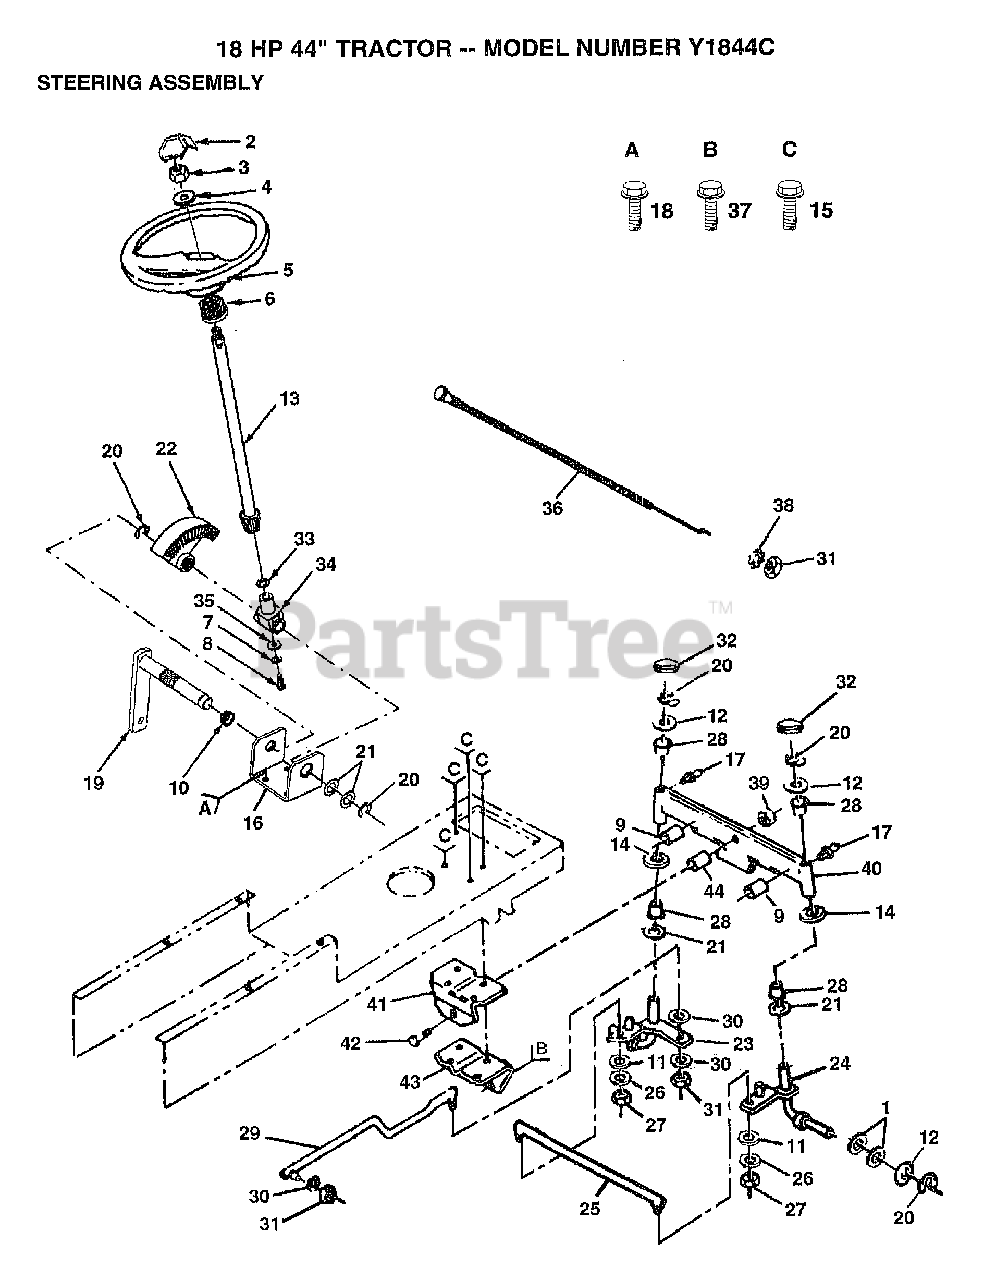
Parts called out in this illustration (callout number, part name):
1	WASHER
2	INSERT STEERING
4	WASHER
6	ADAPTER LT
7	LOCKWASHER
8	"SCREW,SPECIAL"
9	AXLE PIN
10	NYLINER T
11	WASHER M
12	WASHER
14	WASHER
15	SCREW SPECIAL
16	"BRKT,STEERING"
17	ZERK M
18	SCREW
20	RING
21	WASHER .T
22	GEAR SECTOR
23	SPINDLE LH
24	SPINDLE RH
25	TIE ROD
26	LOCKWASHER
27	NUT.LOCK.5/16-24
28	COL. SRTG. BEAR.
30	LOCKWASHER
32	CAP
33	THRUST WASHER
34	SUPPORT.SHAFT
37	SCREW LT
38	LOCKWASHER
39	"NUT-LOC,FLANGE LT"
40	FRONT AXLE
41	SUPPORT-SADDL T
42	BOLT LT
43	SUPPORT.SADDLE.FT
44	BEARING
